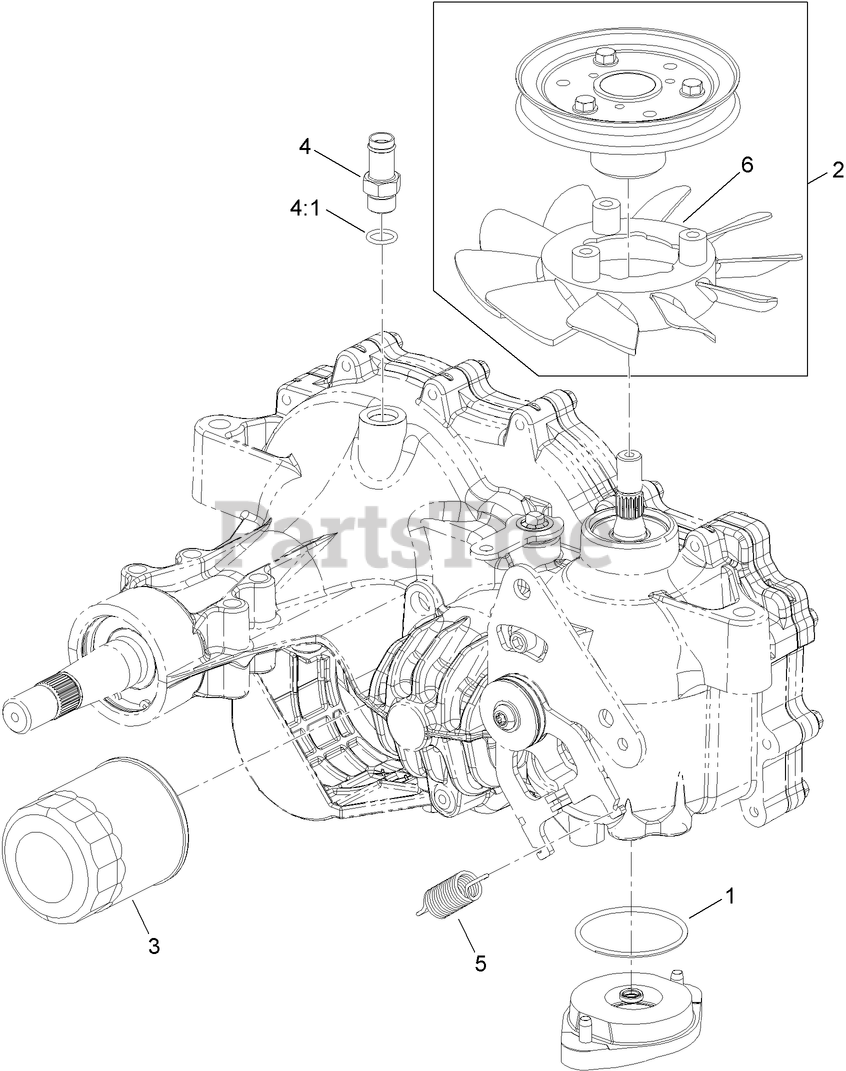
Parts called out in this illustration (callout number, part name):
1	O RING-SEAL
2	FAN AND PULLEY KIT
3	ELEMENT-OIL FILTER, HYD
4	ADAPTER-STRAIGHT
4:1	O-Ring
5	SPRING-EXTENSION
6	FAN-OFFSET, HYDROGEAR
